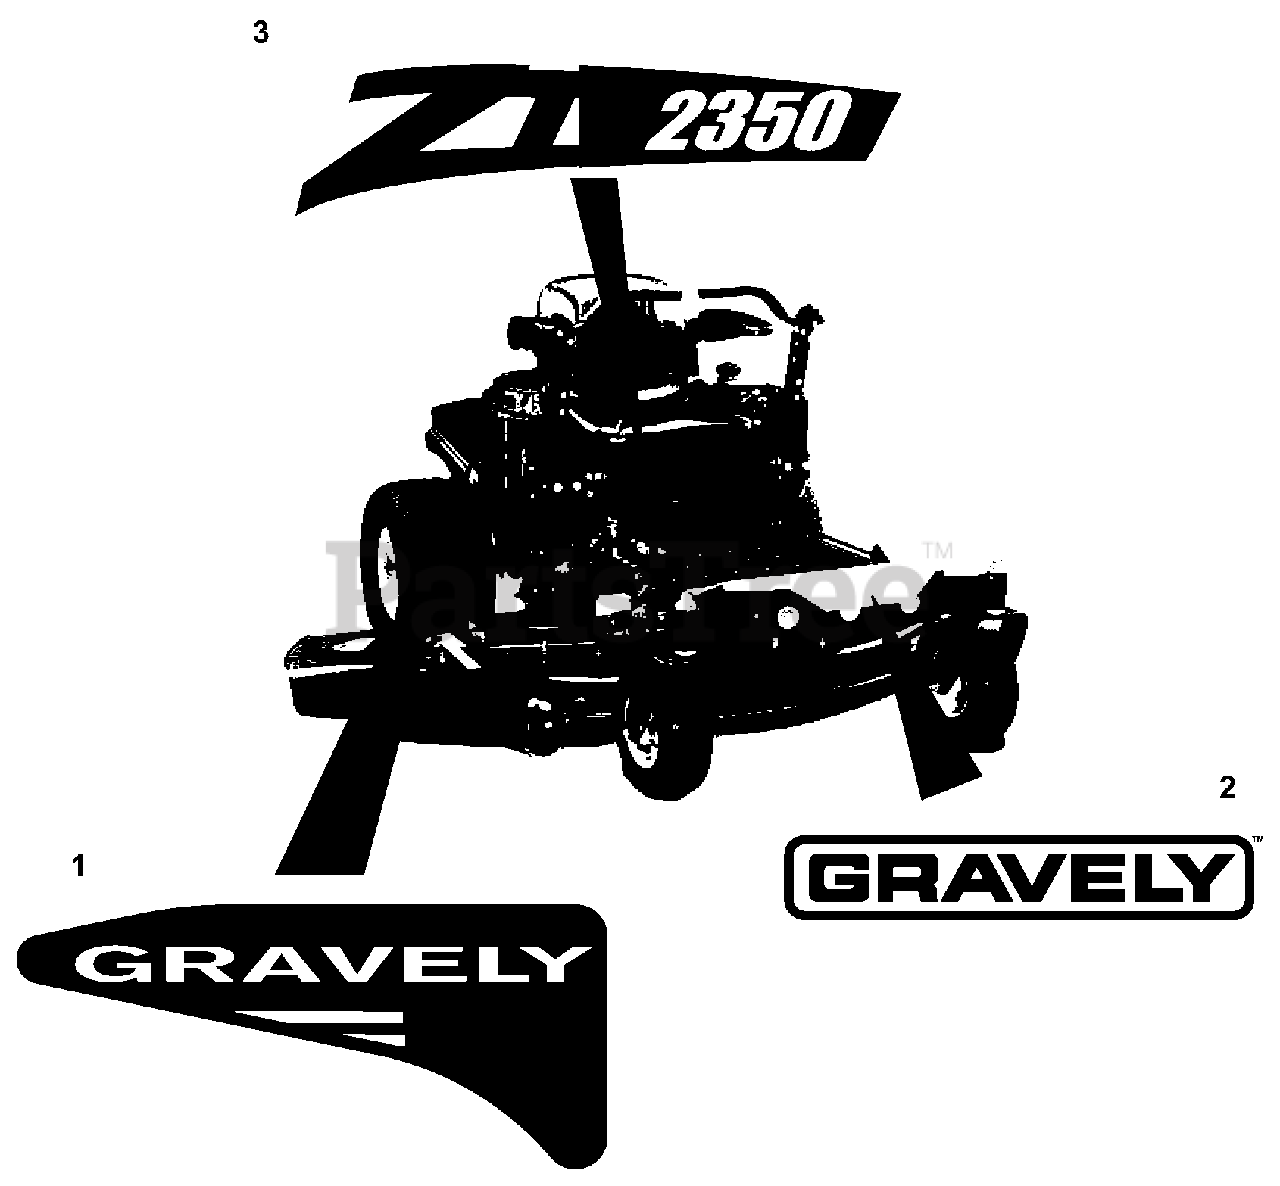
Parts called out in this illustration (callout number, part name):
1	Decal, Gravely Right Hand Tank
2	Decal, Gravely Logo
3	Decal, 2350 ZT
